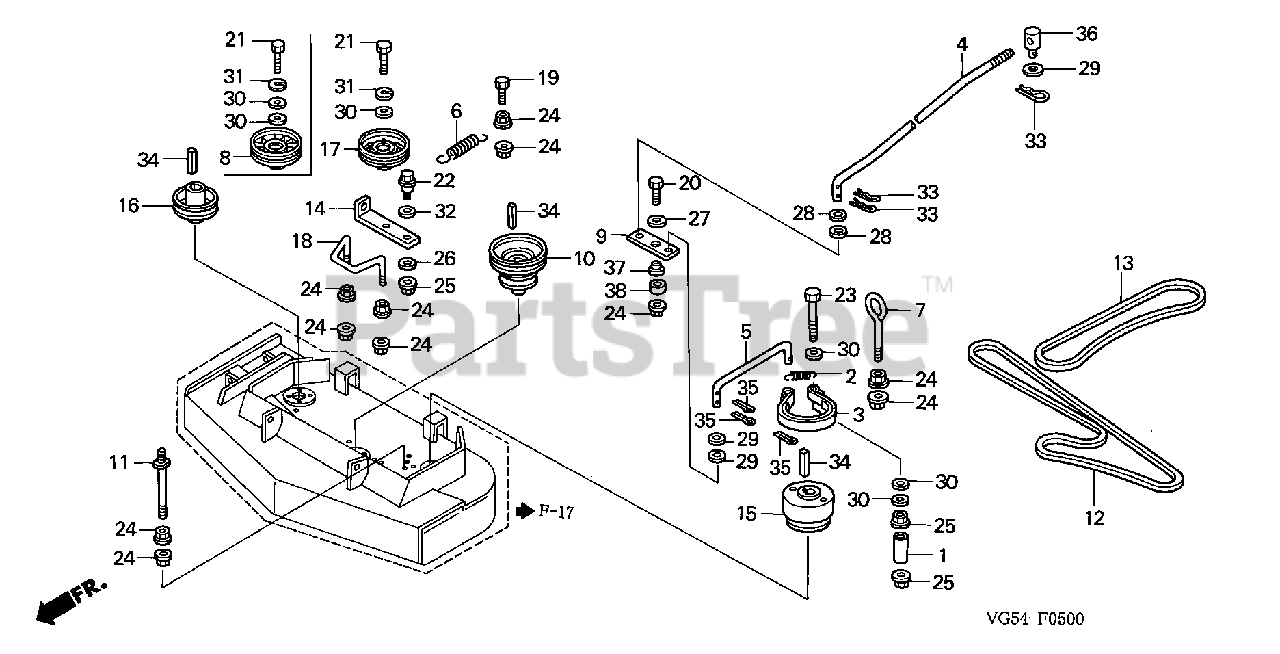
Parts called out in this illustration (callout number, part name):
1	SPACER, R. IDLER
2	SPRING, BRAKE
4	ROD A, BRAKE
5	ROD B, BRAKE
6	SPRING, TENSION
7	BOLT, EYE (5/16-18X4 1/8")
8	PULLEY, V-IDLER
9	PLATE, BRAKE PIVOT
10	PULLEY, BLADE (B)
12	V-BELT, BLADE
13	V-BELT, DECK
14	ARM, IDLER
15	PULLEY, BLADE (A)
18	STOPPER A, BELT
19	BOLT, HEX. (5/16-18X1")
20	BOLT, HEX. (5/16"-18X2")
21	BOLT, HEX. (3/8-16X1 1/2")
22	BOLT, SHOULDER (3/8-16X1")
23	BOLT, HEX. (3/8-16X3 1/2")
24	NUT, WHIZ-LOCK (5/16"-18)
25	NUT, WHIZ-LOCK (3/8"-16)
26	WASHER, FLAT (3/8")
27	WASHER, FLAT (5/16-1 1/8X0.063")
28	WASHER, FLAT (1/4")
29	WASHER, FLAT (5/16")
30	WASHER, FLAT (3/8")
31	WASHER, LOCK (3/8")
32	WASHER (1/2")
33	PIN, LOCK (5/16")
34	KEY (1/4X1/4X2")
35	PIN, COTTER (3/32" X 3/4")
36	PIN, PIVOT (5/16)
37	COLLAR, TENSIONER ARM
38	COLLAR, BRAKE PIVOT
